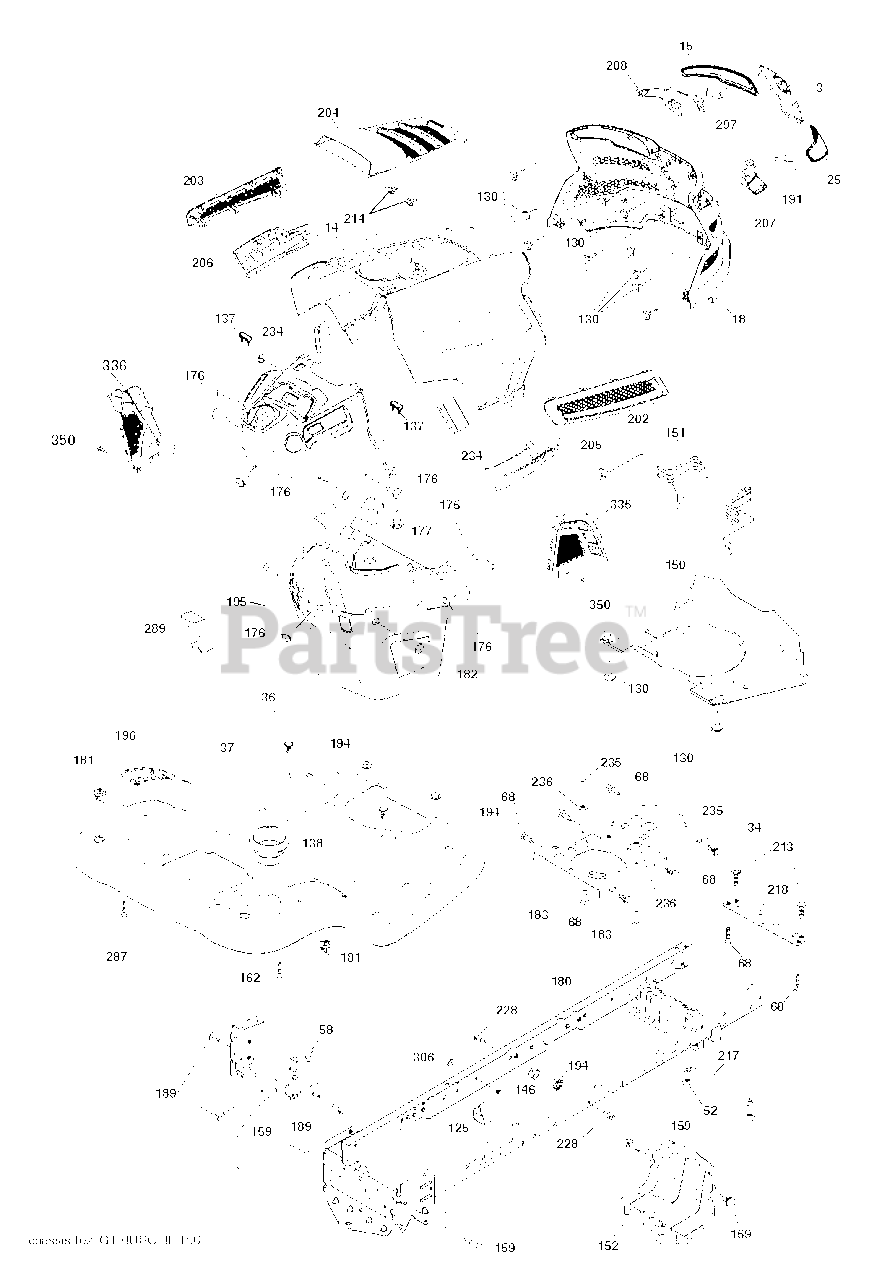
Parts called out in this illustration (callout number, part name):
3	APPLIQUE.SUBASM.GT.HUSQ.II
5	DASH.UPPER.ASSY.GT2.GREY
14	HOOD.ASM.HUSQVARNA.GT.TEX.422
15	LENS.HEADLIGHT.LH.GTII.2011
18	GRILLE.SUBSTRATE.2011.
25	LENS.HEADLIGHT.RH.GTII.2011
34	PLATE.ENGINE.WELDED.CHASSIS
36	SCREW 5/16"
37	RP FENDER.TLT.FS.W/CPH.422
52	LOCKNUT
58	DRAWBAR UPPER 2PC SMALL FENDER
68	SCREW LT
125	CLIP.FUEL.LINE
130	SCREW.#10 X 0.750.BOS
137	BUMPER DASH
138	HOLDER.CUP.LT.GREY
146	BOLT.RDHD.SHT.SQNK.3/8-16X5/8
150	AIR.DUCT.GTV2(2.54"RING HEIGHT
151	BRACKET.PIVOT.HOOD.GT.HUSQ.II
152	SHIELD.BROWNING.PNT.GT.V2
159	SCREW, 3/8-16X3/4
162	SCREW.HI-LO.CONSOLE
175	PLATE.CROSSMEMBER.HUSQ
176	SCREW.#10-24X5/8.RN.QU
177	BUSHING, STEERING
180	CHASS.WLDMNT.TL.12GA/2P.48/54
181	BUSHING.MNT.FEND.CRGO.TEX.49
182	DASH.LOWER.COMMON.12V.ADAPTOR
183	BOLT.5/16-18X1-1/4 FULL THD
189	SCREW
191	INSERT.REFLECTIVE.RH.HUSQ.GTII
194	NUT LOCK HEX FLANGE 5/16-18
195	DECKLFT.CONSOL FULL ASSM GREY
196	CONSOLE.ASM.DCKLFT.RBT.TLT.498
202	VENT.SIDE.RH.GT.HUSQ.II.
203	VENT.SIDE.LH.GT.HUSQ.II.498
204	VENT.TOP.HUSQ.GT2
205	SIDE.TRIM.RH.GT.HUSQ.II
206	SIDE.TRIM.LH.GT.HUSQ.II.GRAY
207	BEZEL LIGHT.RH.GT.II.MYLAR
208	BEZEL LIGHT.LH.GT.II.MYLAR
213	BOLT
214	CLIP.RETAINER.TINNER.
217	ROD.PIVOT.HOOD
218	X-PIECE.HOOD.STOP.NON/
228	STUD.FASTNER.W/ANTI-ROTATE
234	BUMPER.HOOD.TEX.HUSQVARNA
235	SPACER FENDER
236	NUT.CENTERLOCK.5/16-
287	SCREW 1/4X20
289	PLUG.N/CRUISE.COMMON.YT/GT.BLK
297	INSERT.REFLECTIVE.LH.HUSQ.GTII
306	NUT LOCK FLG 3/8-16 UNC
335	COVER.RH.CLOSE.OUT.BLACK
336	COVER-LH.LOWER.DASH.GT2.BLACK
350	CLIP.X-MAS.TREE
